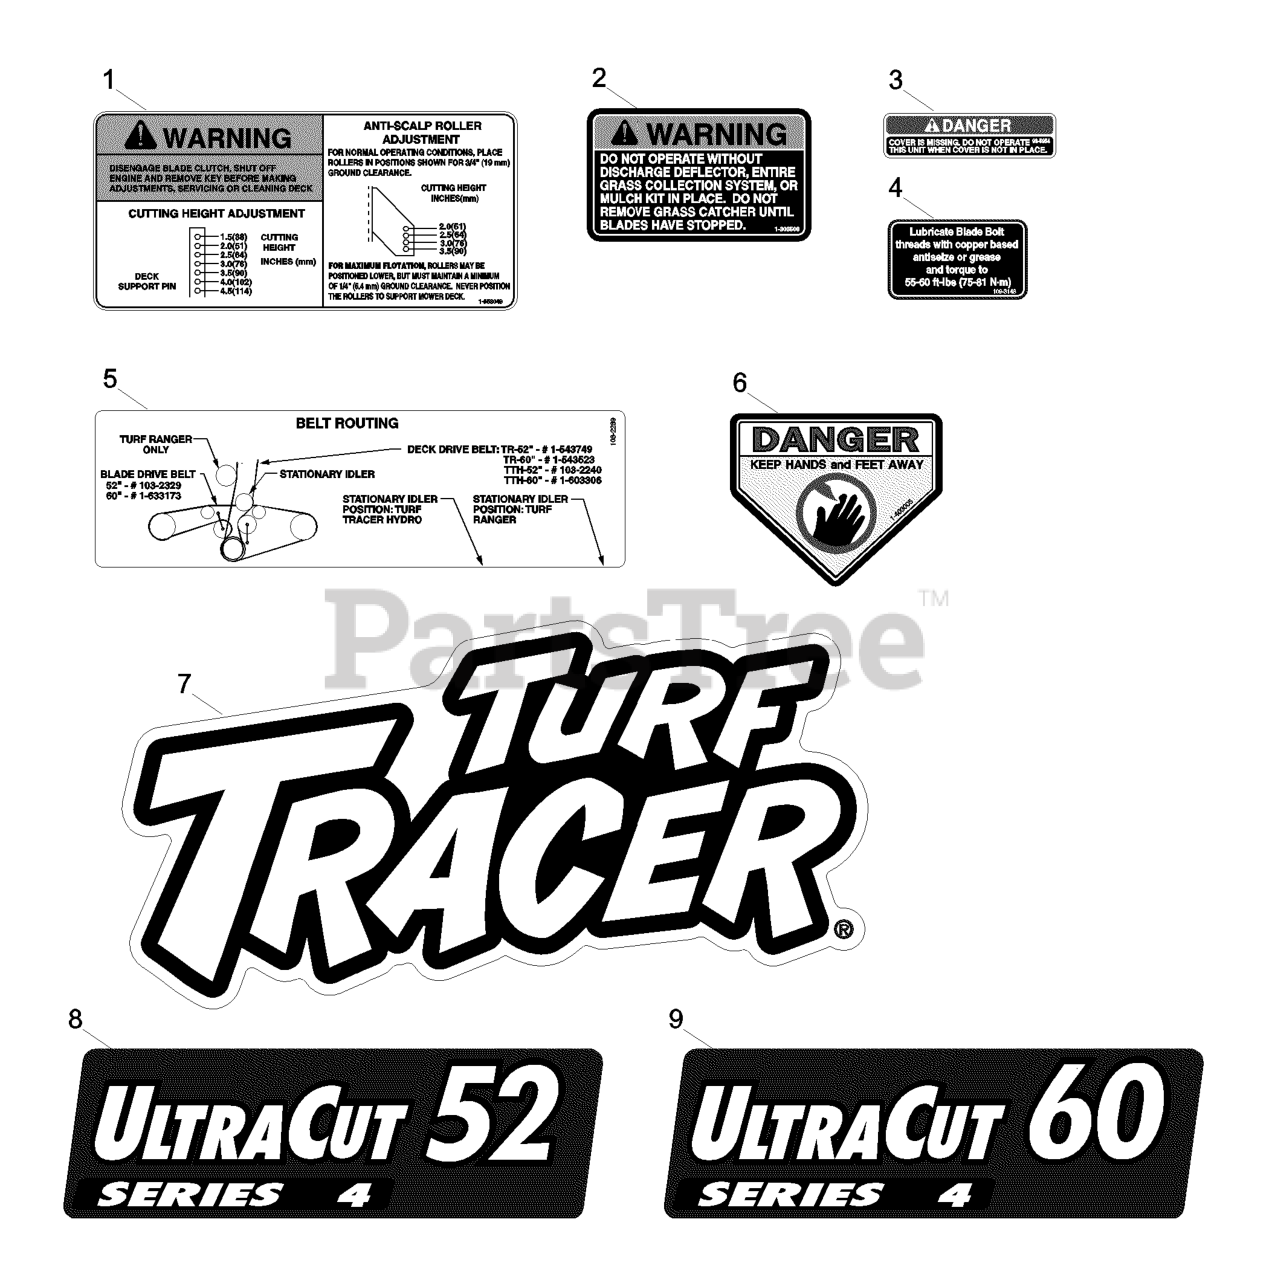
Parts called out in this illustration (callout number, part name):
1	DECAL,ANTI SCALP
2	DECAL-WARNING, DISCHARGE
3	DECAL-COVER, MISSING
4	DECAL,BOLT TORQUE
5	DECAL,BELT ROUTING
6	DECAL-DANGER
7	DECAL,TTH MODEL
8	DECAL,ULTRACUT 52 SERIES
9	DECAL,ULTRACUT 60 SERIES
